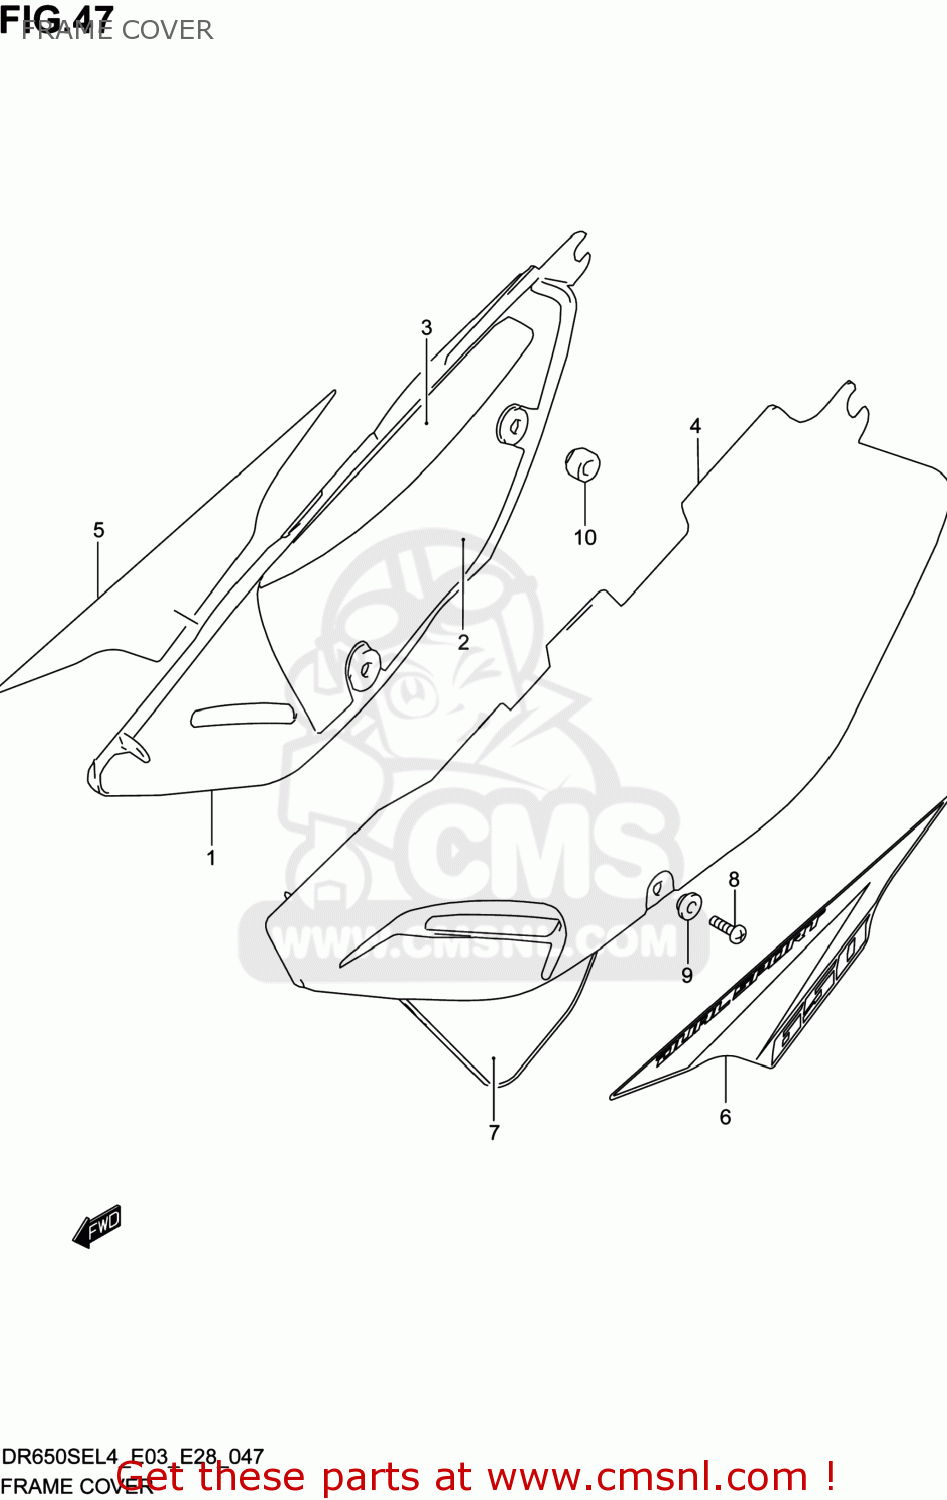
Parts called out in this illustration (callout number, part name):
1	COVER,FRAME,R(GRAY)
2	SHIELD,FRAME COVER,R NO.1
3	SHIELD,FRAME COVER,R NO.2
4	COVER,FRAME,L(GRAY)
5	TAPE,FRAME COVER,R
6	TAPE,FRAME COVER,L
7	TAPE,LWR
8	SCREW
9	WASHER
10	CUSHION
